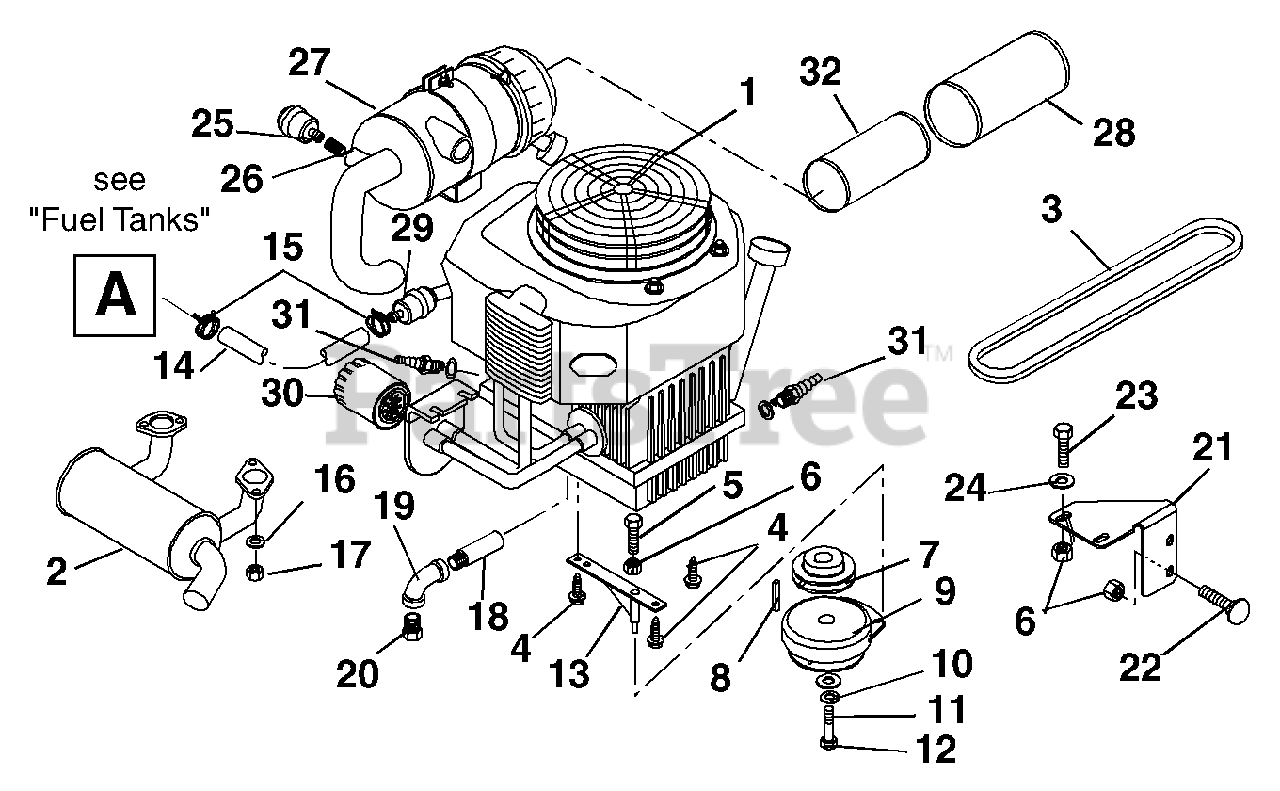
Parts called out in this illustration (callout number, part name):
1	ENG,25HP KOHLER W/RMT OILFILTR
2	MUFFLER, KOHLER
3	V-BELT, HA-RAW EDGE
4	@SCR-TAP .38-16X1.00 HWH TR YZ
5	@BLT-HEX .31-18X1.50 GR5 YWZC
6	@NUT-LK-TOP-FLG .31-18 YWZC
7	PLY-V 4.00 X 1.12 KEYWAY 1.54
8	KEY-SQ .25X.625X.25 SAE 8630
9	ELECTRIC CLUTCH
10	WSHR-FL-STL .515X1.625X.250 YZ
11	@WSHR-LK .44X.109 REG YWZC
12	BLT-HEX .44-20X2.50 GR5 YWZC
13	WMT, CLUTCH ANCHOR
14	GAS LINE-BULK 1/4" I.D.
15	CLAMP-HOSE WIRE .490/.510X.116
16	@WSHR-LK .31X.078 REG YWZC
17	NUT-HEX M8-1.25 YWZC
19	ELBOW .375-18 NPTF
20	PIPE PLUG
21	BRKT, OIL FILTER MTG - BLACK
22	@BLT-RHDSSQNK .31-18X.62 G5YZ
23	@BLT-HEX .31-18X1.00 GR5 YWZC
24	@WSHR-FL-STL.38X.875X.083 YWZC
25	FILTER MINDER
26	NIPPLE, 1/8"NPT
27	AIR CLEANER ASSEMBLY
28	ELEMENT, OUTER PRIMARY
29	FILTER, FUEL
30	FILTER, OIL - KOH CV20
31	SPARK PLUG
32	ELEMENT, INNER SAFETY
